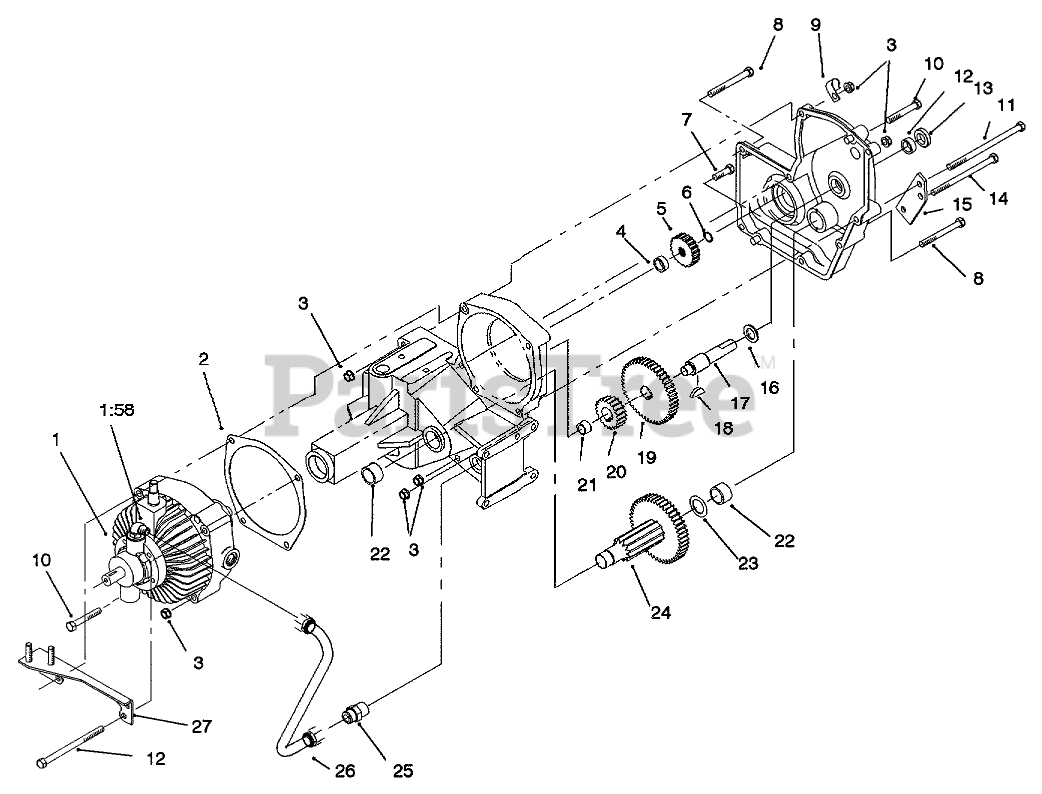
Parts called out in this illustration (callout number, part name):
1	TRANSMISSION-PUMP
2	GASKET
3	NUT-LOCK, NI
4	SPACER GEAR
5	GEAR 20 TEETH DRIVE
6	RING-SNAP, EXTERNAL
8	SCREW-HH
9	CLIP
11	SCREW-HH
12	NEEDLE BEARING
13	Seal
14	SCREW-HH
15	Bracket-Brake
16	Race Thrust
16:1	Case-Transaxle
16:2	DECAL - DANGER
17	SHAFT GEAR
18	Key
19	GEAR 46 TEETH
20	GEAR 20 TEETH
21	BEARING-NEEDLE
22	BEARING-NEEDLE
23	WASHER-THRUST
24	ASSY GEAR
25	FITTING-TUBE
26	ASSY-TUBE SUCTION
27	Plate-Control
